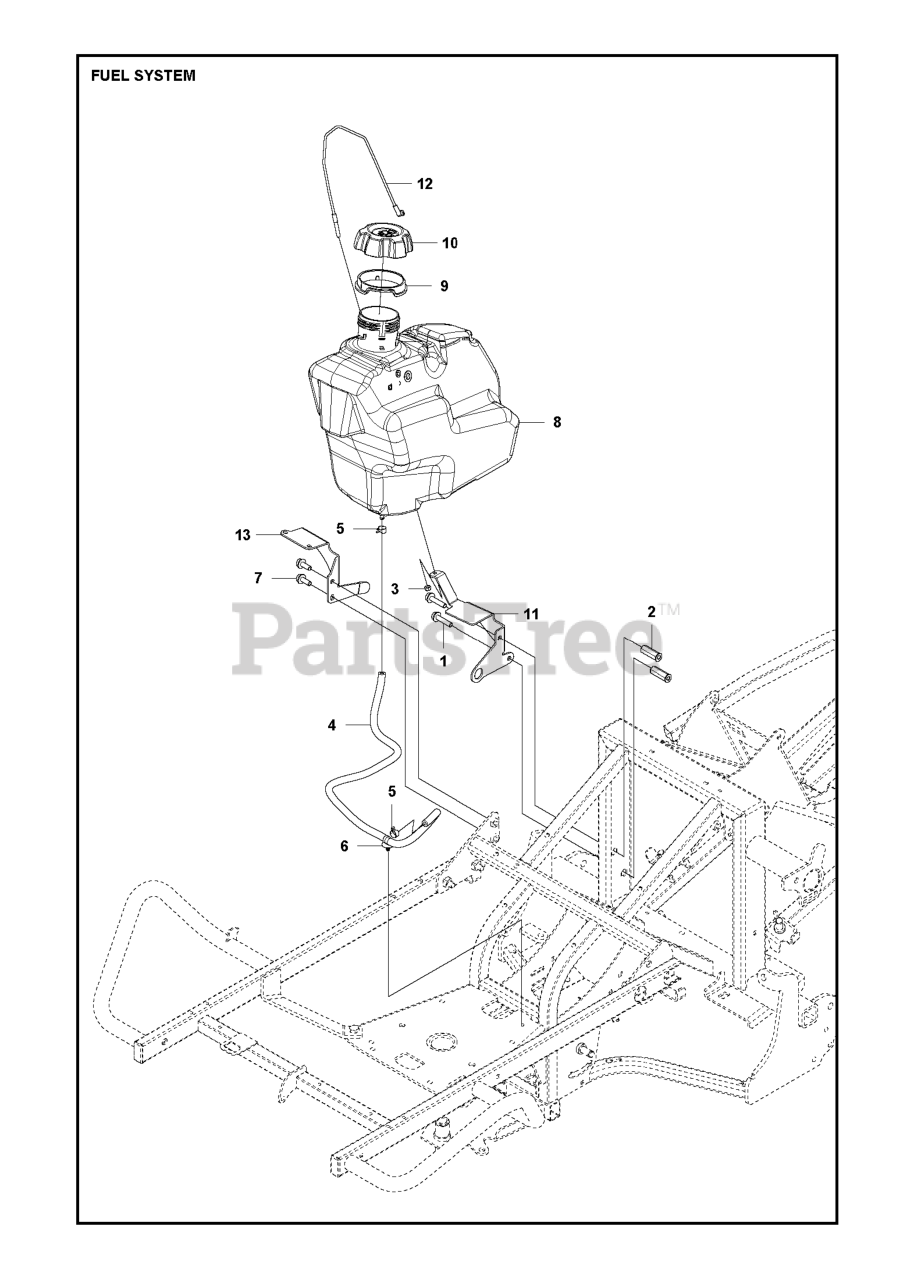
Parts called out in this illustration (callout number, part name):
1	SCREW EHHFM
3	LOCKNUT M6
9	LOCKING NUT
10	CAP.ASSY.FUEL.3".N-EPA.GRY.498
